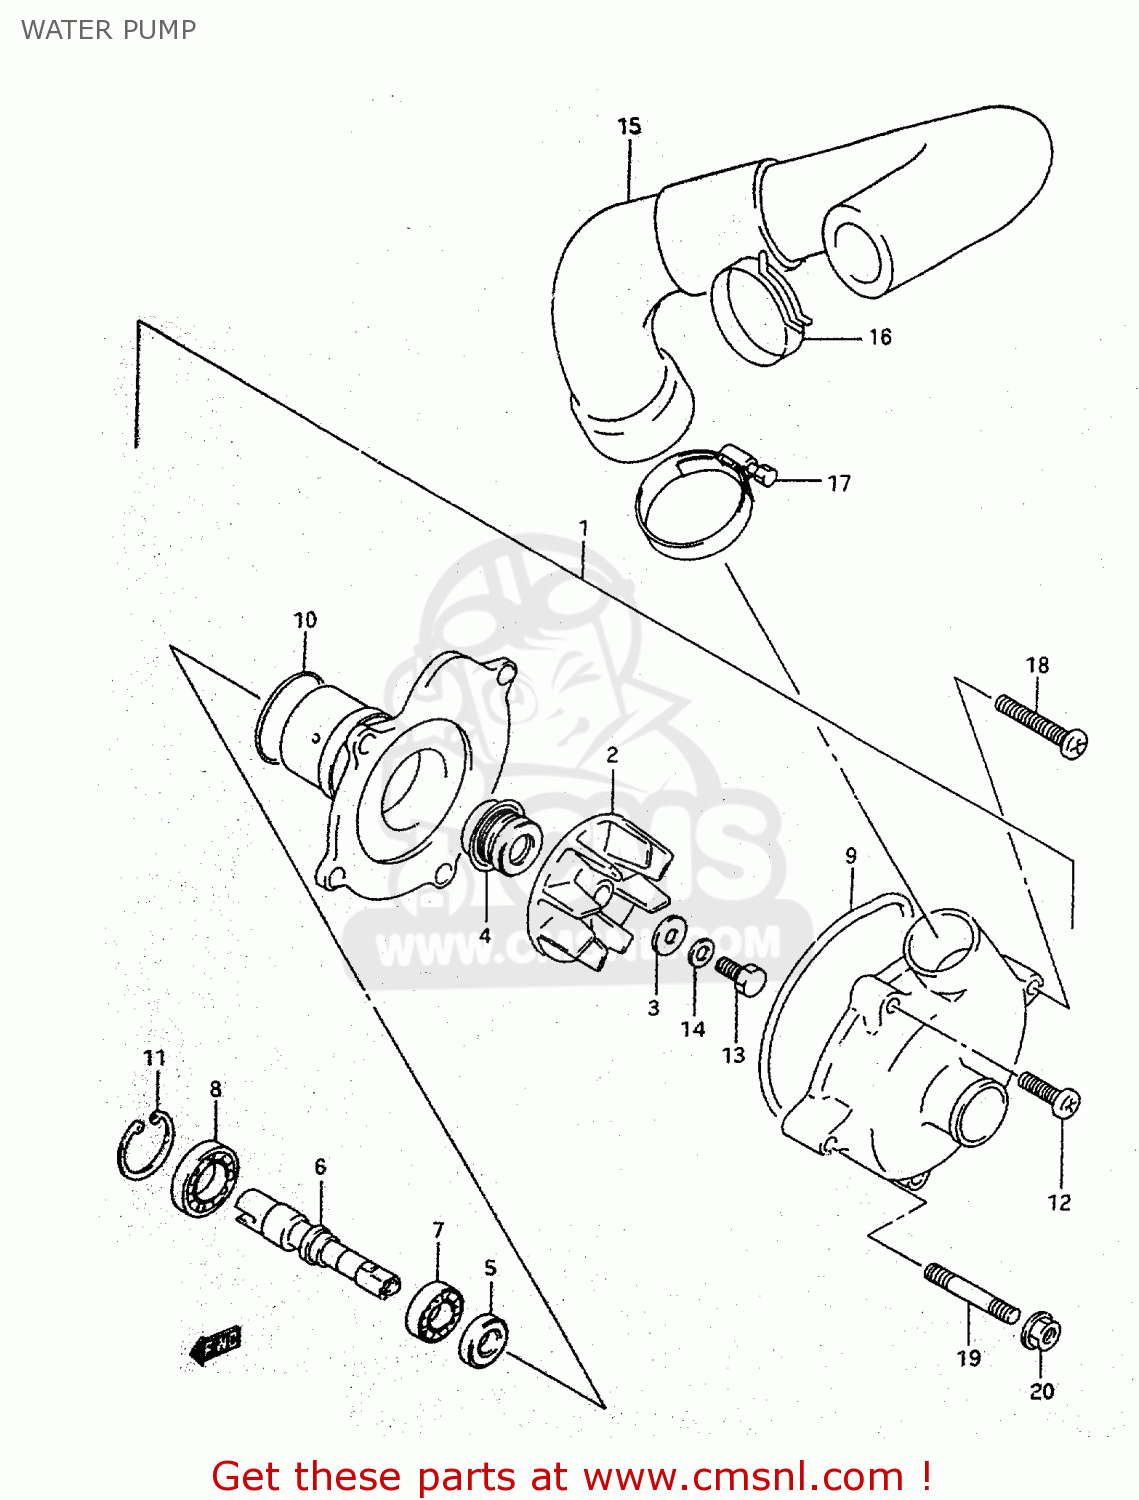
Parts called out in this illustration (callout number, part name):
1	PUMP ASSY,WATER
2	IMPELLER
3	GASKET(6X15X2.2) (NAS)
4	SEAL,MECHANICAL
5	OILSEAL
6	SHAFT
7	BEARING
8	BEARING(12X28X8)
9	O RING
10	O RING,WATER PUMP HOLDER
11	CIRCLIP
12	SCREW
13	BOLT(6X13)
14	WASHER
15	HOSE,WATER PUMP OUTLET
16	CLAMP
17	CLAMP
18	SCREW
19	BOLT,STUD
20	NUT
